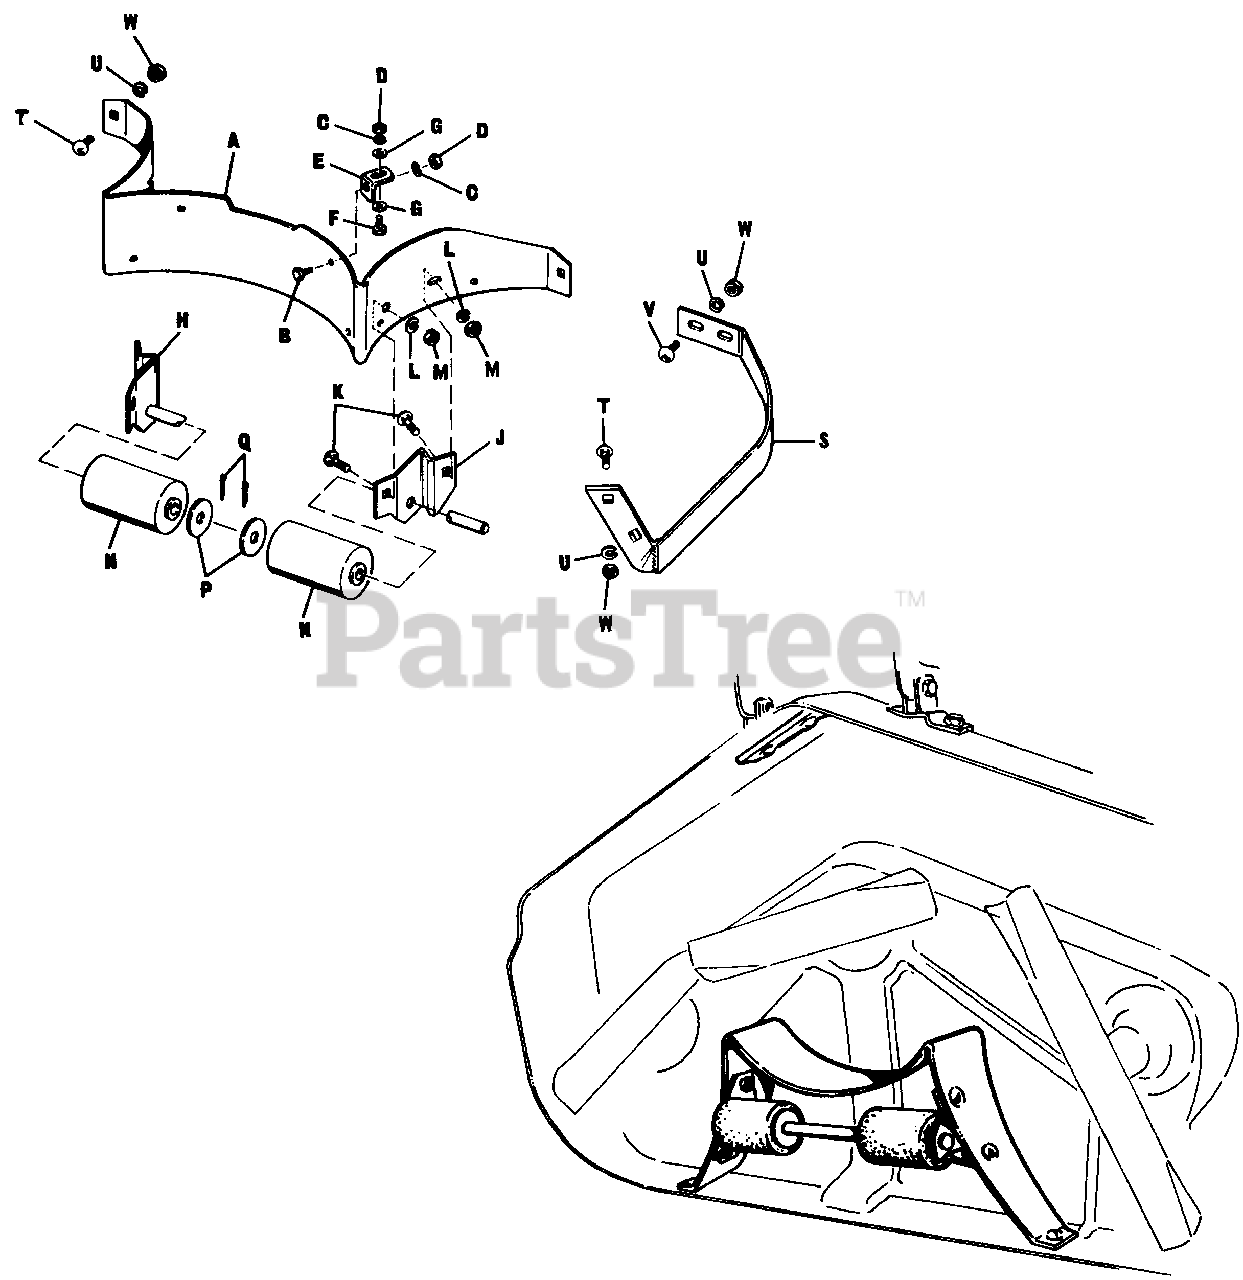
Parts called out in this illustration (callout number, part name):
B	Self Tap Hex. Screw, 1/4"-20 x 7/8
C	Lock Washer, 1/4"
D	Full Hex. Nut, 1/4"-20
E	Baffle Clip
F	Hex. Cap Screw, 1/4"-20 x 5/8"
G	Plain Washer, 1/4"
H	Bracket & Shaft Assembly
J	L.H. Roller Bracket
K	Carriage Bolt, 5/16"-18 x 3/4"
L	Lock Washer, 5/16"
M	Full Hex. Nut, 5/16"-18
N	Roller Assembly w/Bushing
Q	Cotter Pin, 5/16"-1"
S	Housing Assembly Guard
T	Carriage Bolt, 3/8"-16 x 3/4"
U	Lock Washer
V	Carriage Bolt 3/8"-16 x 1"
W	Full Hex. Nut, 3/8"-16
